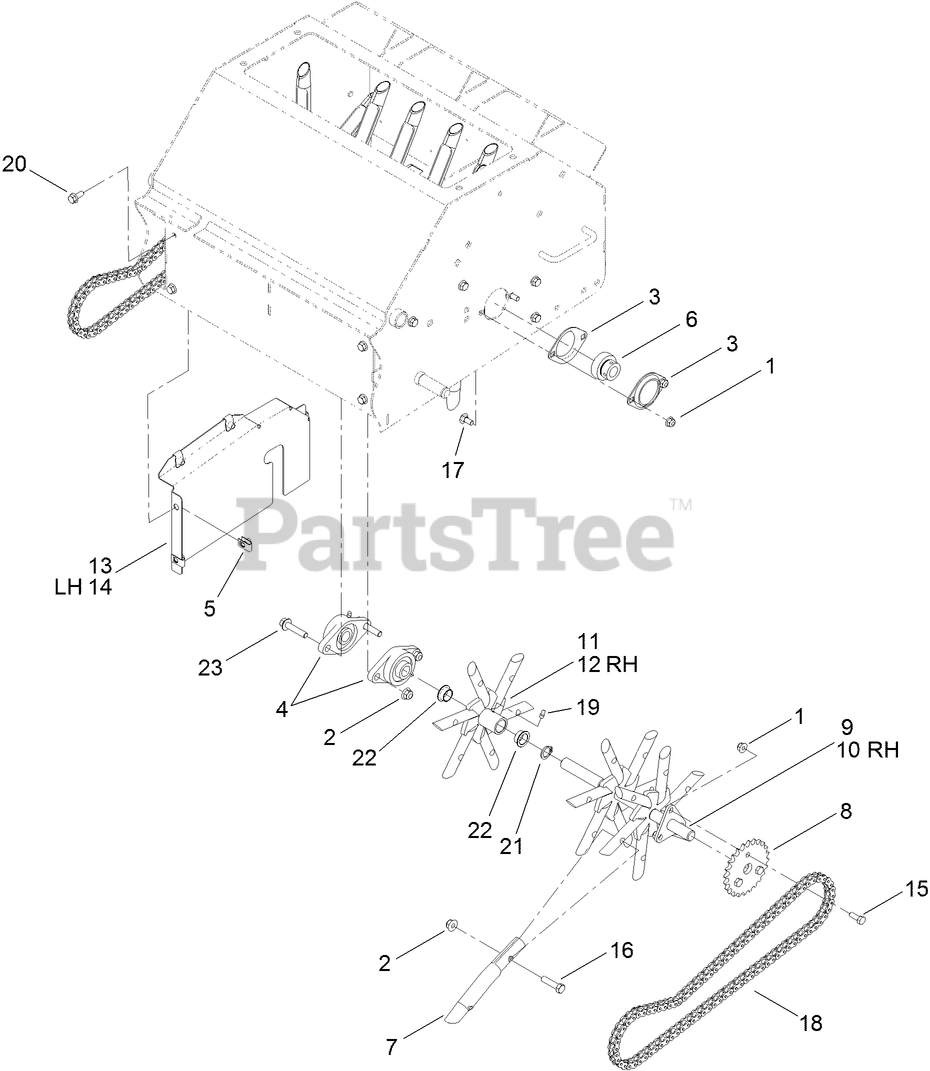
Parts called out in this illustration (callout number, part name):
1	NUT-HF, NI
2	NUT-HF, NI
3	FLANGE-BEARING
4	BEARING-FLANGE
5	NUT-CLIP, U
6	BEARING-LOCK, COLLAR
7	TINE-CORING
8	SPROCKET
9	TINE-WHEEL, LH
10	TINE-WHEEL, RH
11	SPYDER TINE ASM
12	SPYDER TINE ASM
13	GUARD-CHAIN, RH
14	GUARD-CHAIN, LH
15	SCREW-HH
16	SCREW-HH
17	BOLT-CARR
18	CHAIN-DRIVE
19	FITTING-GREASE
20	SCREW-HHF
21	RING-RETAINING
22	BUSHING-BRONZE
23	SCREW-HHF
